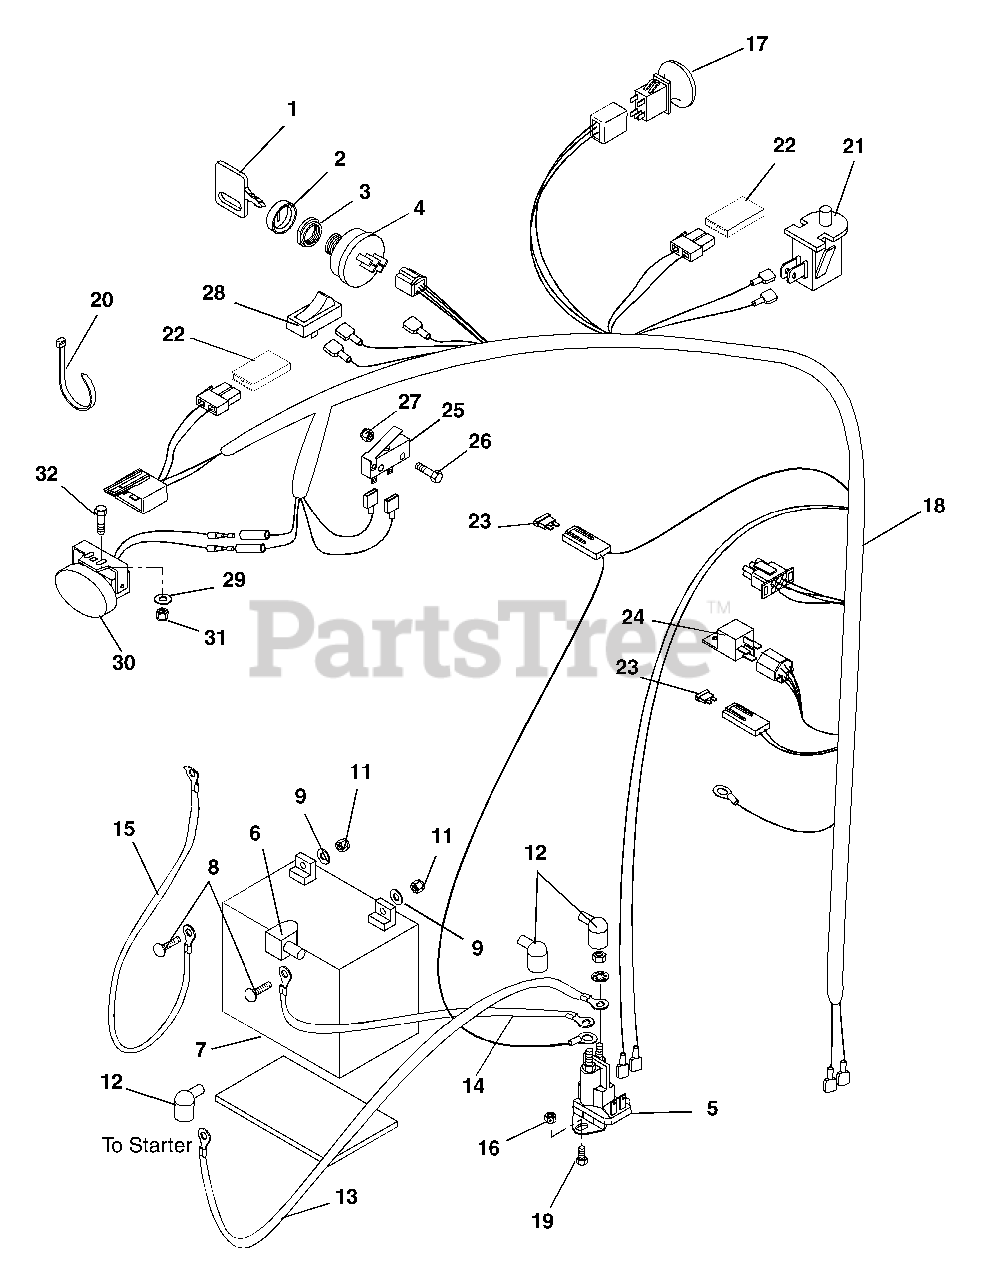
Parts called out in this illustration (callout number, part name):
1	KEY -W/CAP
2	CAP - IGNITION SWITCH
3	NUT- PANEL .562-24 GRECO
4	SWITCH KEY 5Y463A ALT GRDNG
5	SOLENOID
6	INSULATOR
7	BATTERY, 300 CCA 10U1L
8	@BLT-RDHDSQNK .25-20X.75 G5YZ
9	@WSHR-FL-STL.281X.62X.065 YWZC
10	@WSHR-LK .25X.062 REG YWZC
11	@NUT-HEX .25-20 YWZC
12	BOOT, EYELET TERMINAL
13	STARTER CABLE 13"
14	STARTER CABLE 16"
15	CBL,NEGATIVE BATTERY 20.00
16	@NUT-SPNLK-FLG .312-18 YWZC
17	SWITCH, CLUTCH
18	WIRE HARNESS - RER
19	@SCR-TAP 10-24X.375 HWH YZ TR
20	CABLE TIE LG 5-1/2
21	SWITCH- SNAP MTG N.O.
22	DIODE, CONNECTOR SHELL
23	FUSE-25 AMP ATC TYPE
24	RELAY
25	SWITCH, RER PARK BRAKE
26	SCREW, MACHINE 2-56 X 3/4
27	NUT, NYLK 2-56 PL
28	SWITCH - LIGHT
29	WSHR-FL-STL .328X.87X.179 YWZC
30	LIGHT-CONS RIDE ON- SEE B-2124
31	@NUT-LK-TOP-FLG .31-18 YWZC
32	@BLT-RDHDSQNK .31-18X1.00 G5YZ
